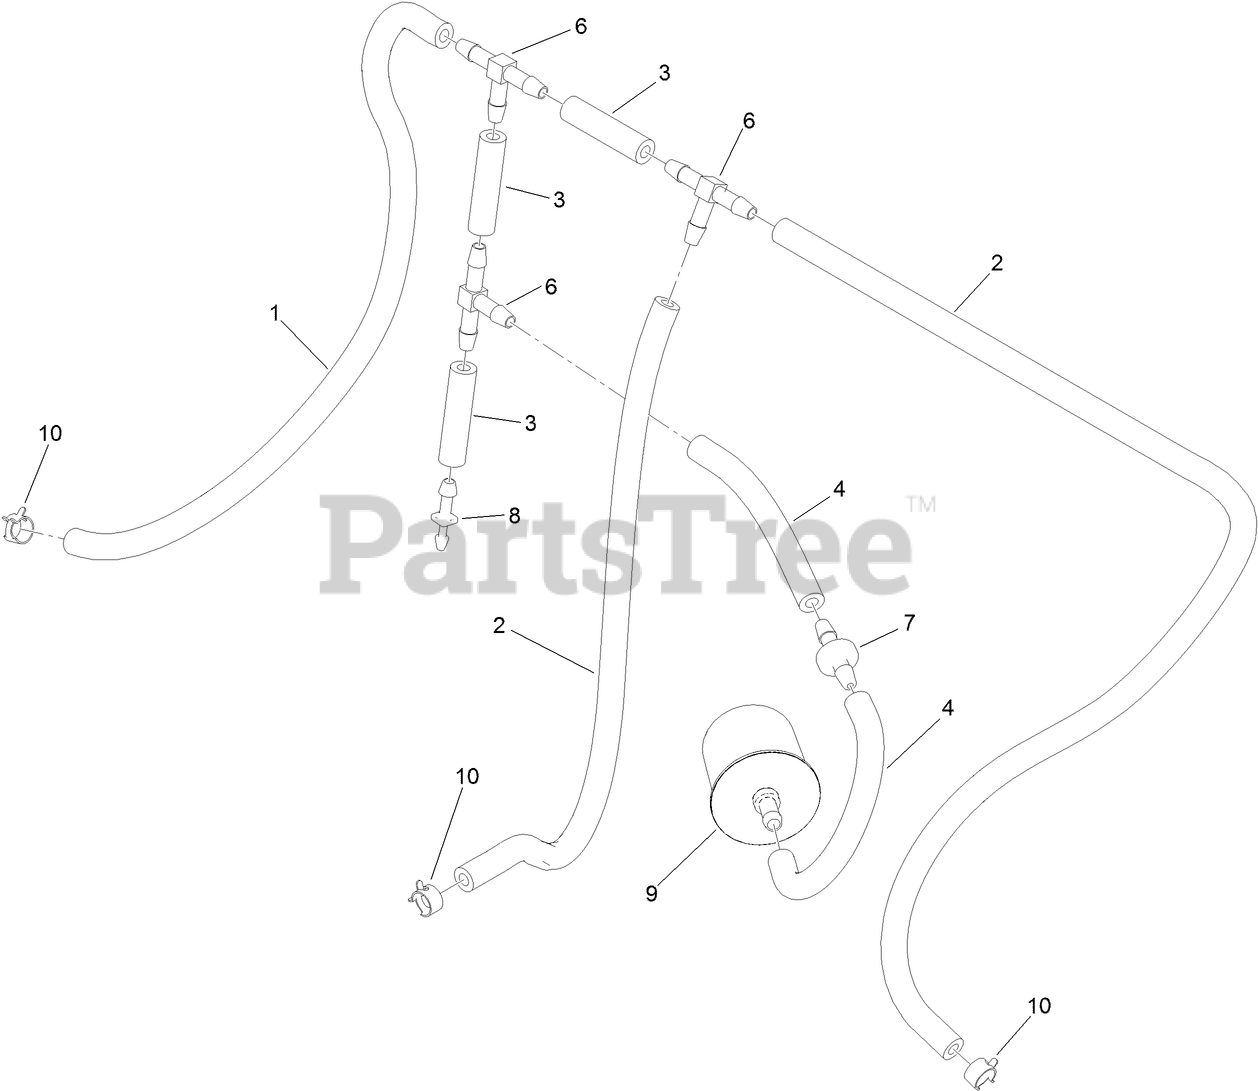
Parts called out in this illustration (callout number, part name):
1	HOSE-FUEL
2	HOSE-FUEL
3	HOSE-FUEL
4	HOSE-FUEL
6	FITTING-TEE, BARBED
7	VALVE-CHECK, FUEL
8	FITTING-STRAIGHT
9	FILTER-FUEL
10	CLAMP-HOSE
